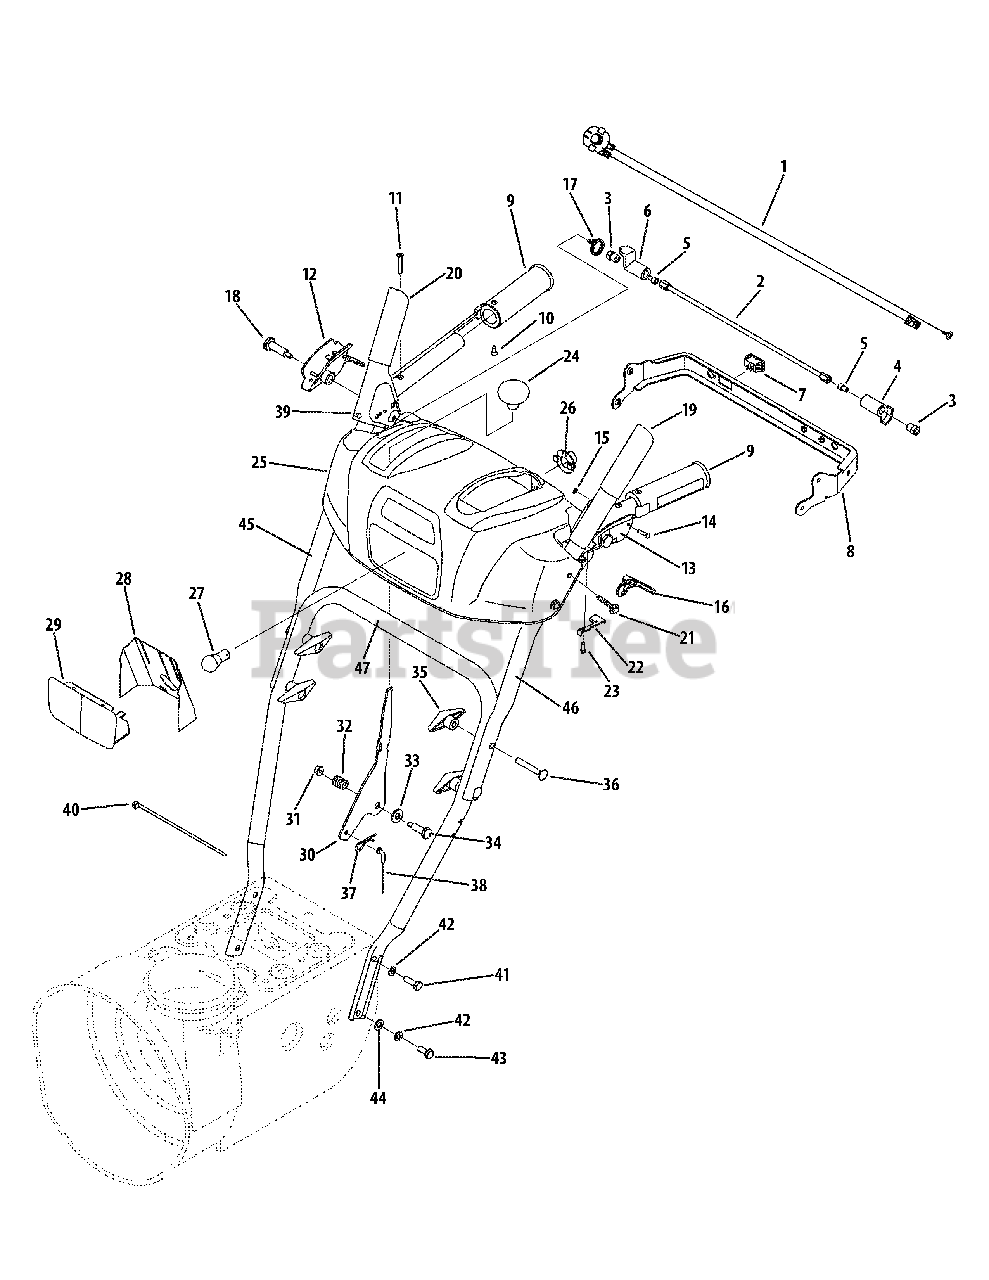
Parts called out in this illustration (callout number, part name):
1	Wire Harness
2	Clutch Lock Rod Assembly
3	Hex Shoulder Nut, 1/4-20
4	Clutch Lock Cam
5	Socket Cap Screw 1/4-20 x .50
7	Heated Grip Switch
8	Panel Bracket
9	Heated Grip
10	AB Screw, #10-16 x .625
11	Machine Screw, #10-24 x 1.375
12	Clutch Lock Handle Assembly, RH
13	Clutch Lock Handle Assembly, LH
15	E-Type Ring, .375
16	Clutch Trigger Lock
17	Torsion Spring, .8156 ID x .3038
18	Shoulder Screw, .437 x 1.345 x /-20
19	Engagement Handle Assembly, LH
20	Engagement Handle Assembly, RH
21	Hex Washer Screw, 1/4-20 x 1.625
22	Clutch Lock Spring
23	Hex Washer Screw, #8-16 x .50
24	Shift Knob
25	Handle Panel
26	Light Socket
27	Lamp
28	Lens Label
30	Shift Lever
31	Flange Lock Nut, 1/4-20
32	Compression Spring, .39 x .60 x .88
33	Flat Washer, .385 x .87 x .06
34	Shoulder Screw, .374 x 1.05
35	Knob Assembly, 5/16-18
36	Carriage Screw, 5/16-18 x 2.25
37	Click Pin, .092 x 1.64
38	Speed Selector Cable
39	Rubber Bumper, .62 x .22
40	Cable Tie, 3/16 x .05 x 7.43
41	Hex Bolt, 5/16-18 x 1.00
42	Lock Washer, 5/16
43	Hex Bolt, 5/16-18 x .75
44	Flat Washer, .344 x .688 x .065
45	Upper Handle, RH
46	Upper Handle, LH
47	Lower Handle
